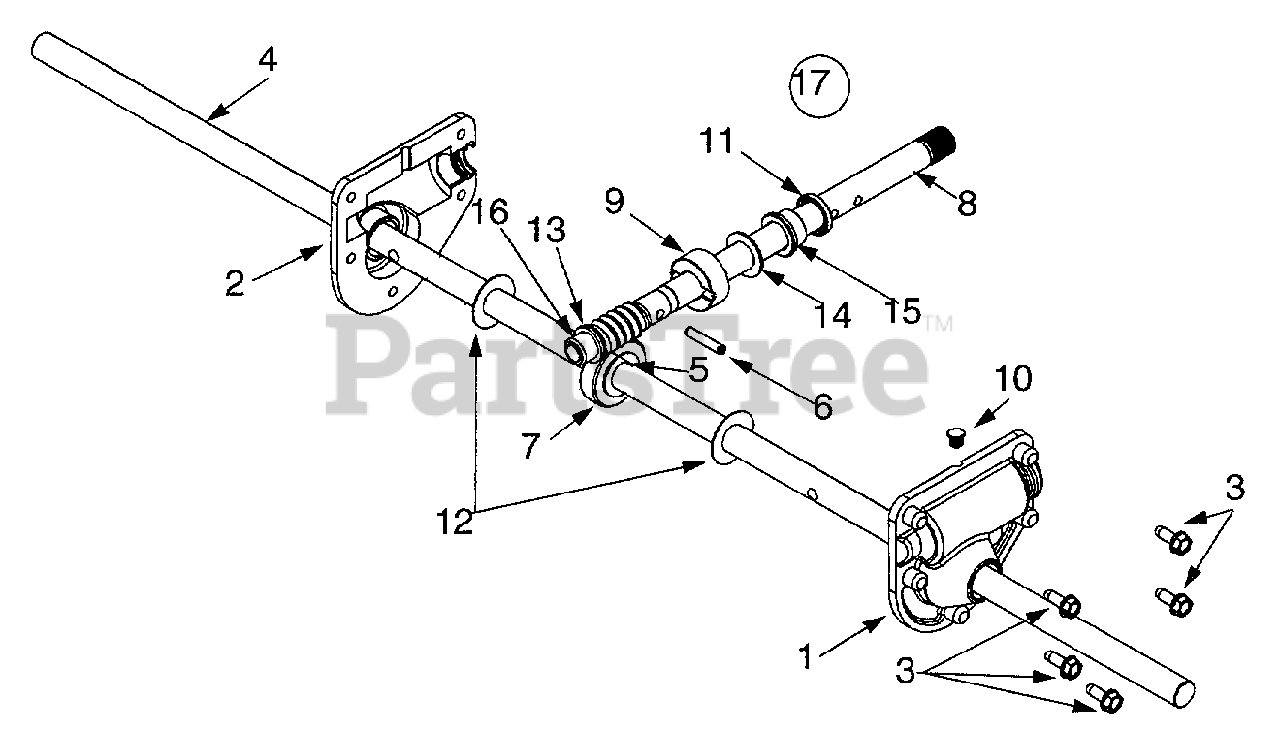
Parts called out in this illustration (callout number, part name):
1	RH Reducer Housing
2	LH Reducer Housing
3	Hex Screw 1/4-20 x .75
4	Spiral Axle: 28"
5	Key
6	Pin-Spiral
7	Worm Gear, 20T
8	Worm Shaft
9	Thrust Collar
10	Grease Plug
11	Grease Seal
12	Flat Washer .76 x 1.5 x .030
13	Flat Washer .508 x 1.0 x .020
14	Flat Washer .76 x 1.5 x .060
15	Flange Bearing .75 x 1.0 x .59
16	Flange Bearing .75 x 1.0 x .925
17	Complete Assembly: 28"
